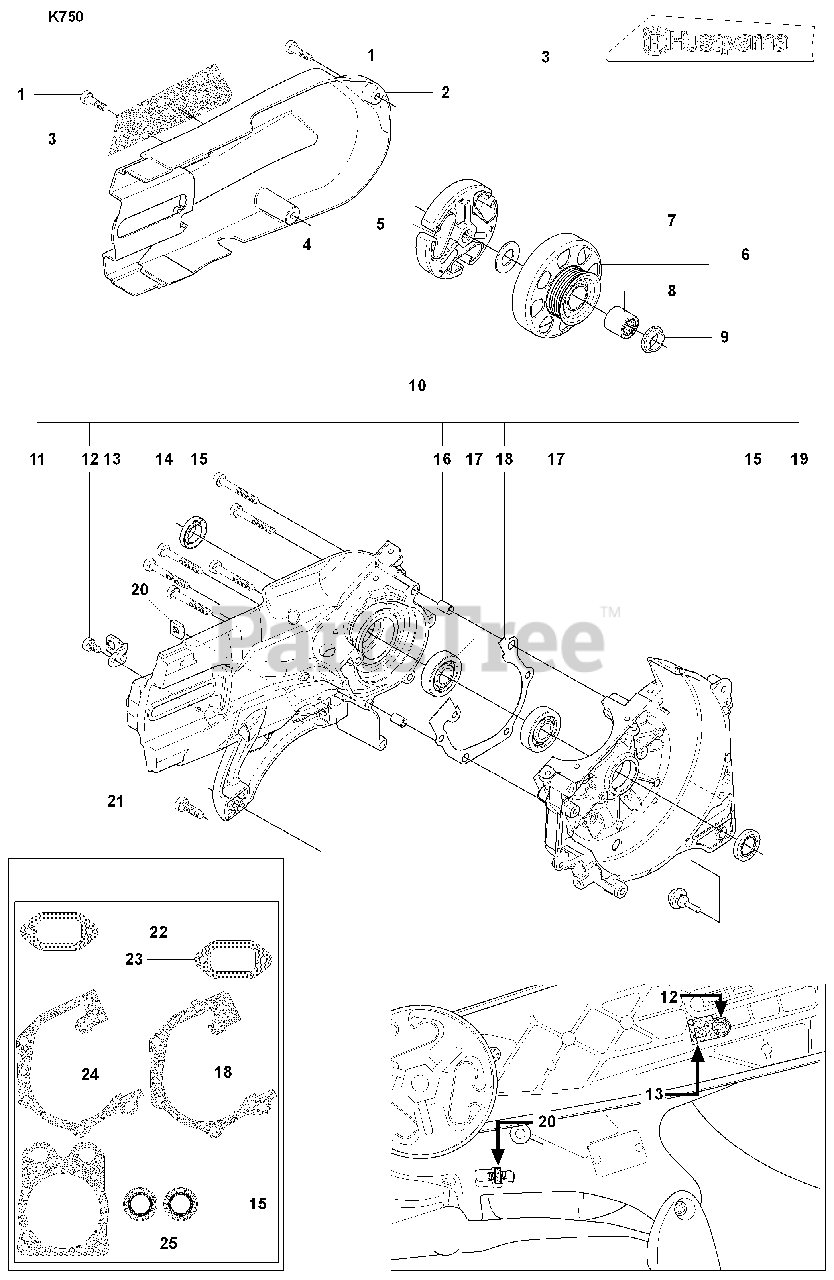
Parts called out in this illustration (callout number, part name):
2	BELT GUARD
4	CLUTCH ASSY
5	CLUTCH SPRING
6	CLUTCH WHEEL
7	WASHER STEEL
8	NEEDLE BEARING
10	CRANKCASE ASSY
11	GASKET KIT
15	SEALING RING
16	GUIDE BUSHING
17	BALL BEARING
18	GASKET CRANKCASE
23	GASKET MUFFLER
24	GASKET CRANKCASE
25	GASKET CYLINDER BASE
